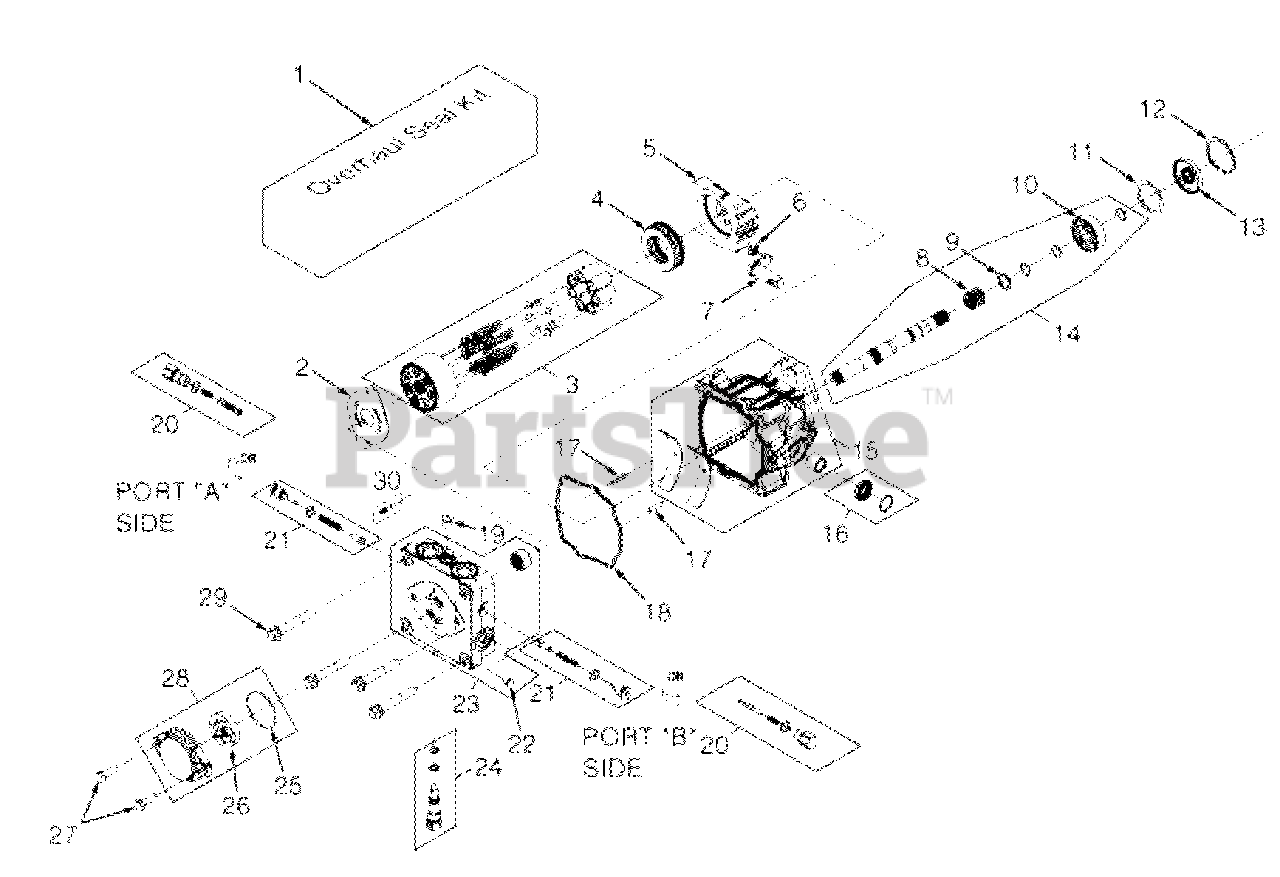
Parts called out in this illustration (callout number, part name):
1	Overhaul Seal Kit
2	Valve Plate
3	Cylinder Block Kit - 16cc
4	Thrust Ball Bearing Assembly
5	Variable Swashplate
6	Slot Guide
7	Trunnion Arm
8	Block Spring
9	Block Thrust Washer
10	Shaft Ball Bearing
12	Retaining Ring
14	Kit, Pump Shaft
15	Housing Kit
16	Trunnion Seal Kit
18	O-Ring
19	Straight Thread Plug
20	Shock Valve Kit (.031 Orifice)
21	Shock Valve Kit (.024 Orifice)
22	Straight Thread Plug
23	End Cap Kit
24	Bypass Valve Kit
26	Gerotor Assembly (.19 cu.in./rev.)
27	Socket Head Cap Screw (M8 x 1.25-25mm)
28	Charge Pump Kit (.19 STD. Splined)
29	Hex Screw, Flanged Head (M10 x 1.50-65mm)
30	Charge Relief Kit
